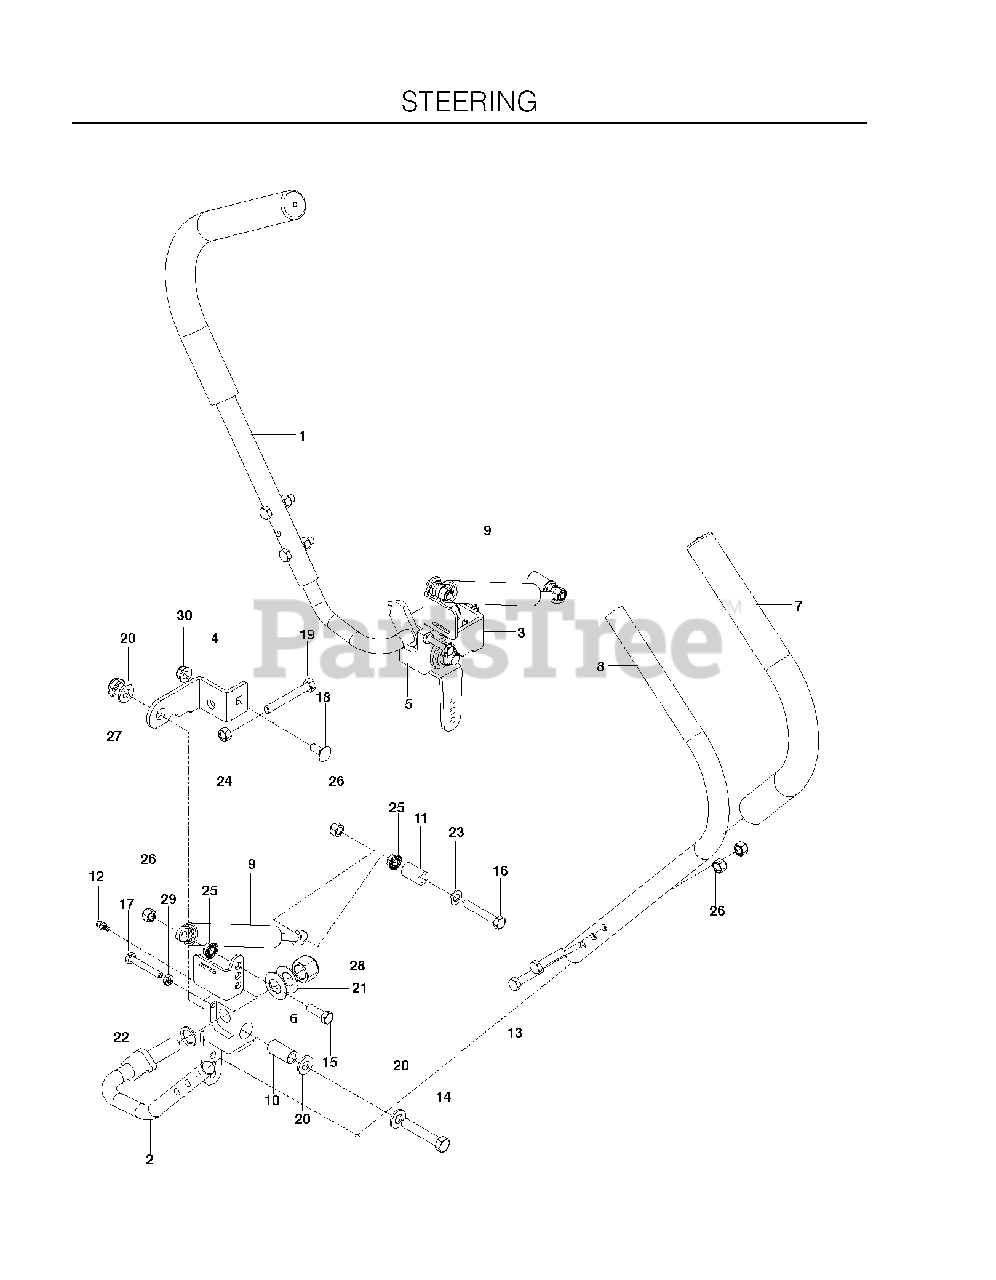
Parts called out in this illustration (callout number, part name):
1	PLATED LEVER RH
2	LEVER PLATED LH
3	FORWARD STOP RH
4	FORWARD STOP LH
5	PIVOT RH (PLATED)
6	PIVOT LH (PLATED)
8	LEVER UPPER
9	DAMPENER, DUAL ACTION
10	BUSHING
11	BUSHING
12	ZERK, 3/16, DRIVE IN
13	CAPSCREW 5/16 X 1/1/2 HEX HEAD
14	HCS 1/2C X 2 3/4
15	HCS 5/16C X 1
16	HCS 5/16-18X2
17	BOLT 1/4C X 1 3/4
18	BOLT 5/16C X 3/4" CARRIAGE
19	HCS 5/16-18 X 2 1/2 TPBLT
20	WASHER 1/2" FLAT
21	WASH 5/8 BEVELED DISC SPRING
22	WASHER-.626IDX.056TK
23	FLAT WASHER 5/16 SAE
24	NUT 5/16C HEX
25	NUT 5/16C WHIZ
26	NUT 5/16 NYLOC
27	NUT 1/2-13 HEX JM NYL
28	NUT 5/8-11 NYLOC
29	NUT 1/4-20 JAM
30	5/16-18 NYLOC FLANGE NUT
